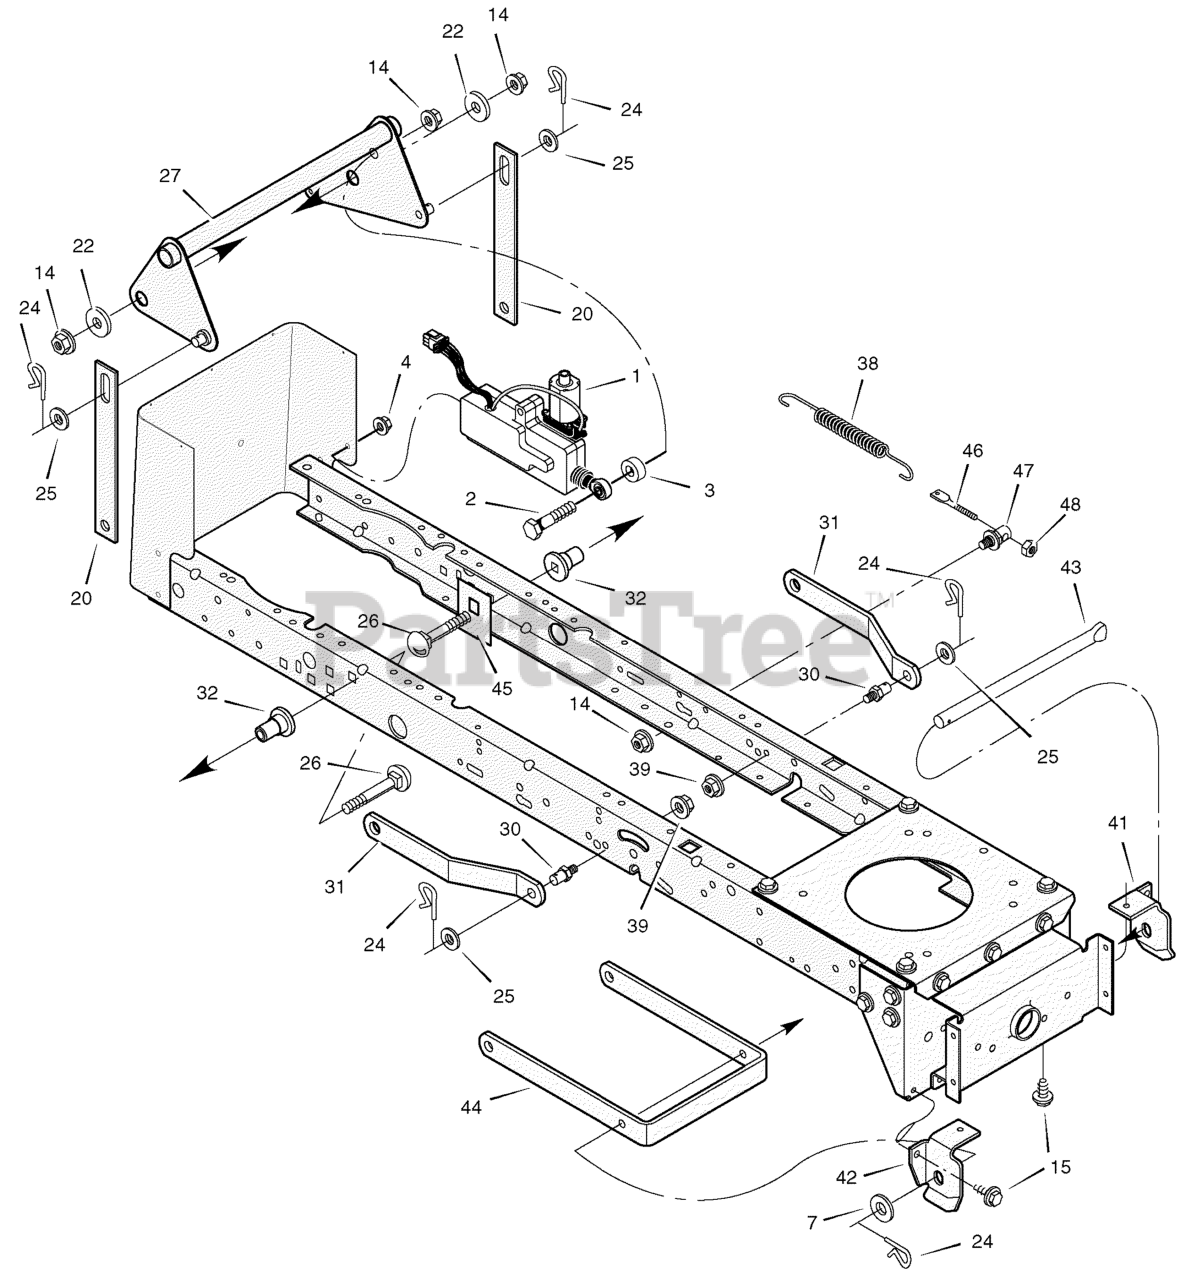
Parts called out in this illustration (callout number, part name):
1	Assembly, Deck Lift
2	Bolt, Hex
4	Nut
7	Washer
14	Nut, Flange
15	Screw
20	Link, Lift
24	Pin, Hair
25	Washer
26	Bolt, Carriage
27	Lever Assembly, Lift
31	Bracket, Rear Suspension
32	Spacer, Lifter
39	Nut, Flange
41	Hanger, Left Deck
42	Hanger, Right Deck
43	Rod, Hanger
44	Bracket, Suspension
45	Plate, Stiffening
46	Stud, Spring Mount
47	Stud, Swivel
48	Nut
